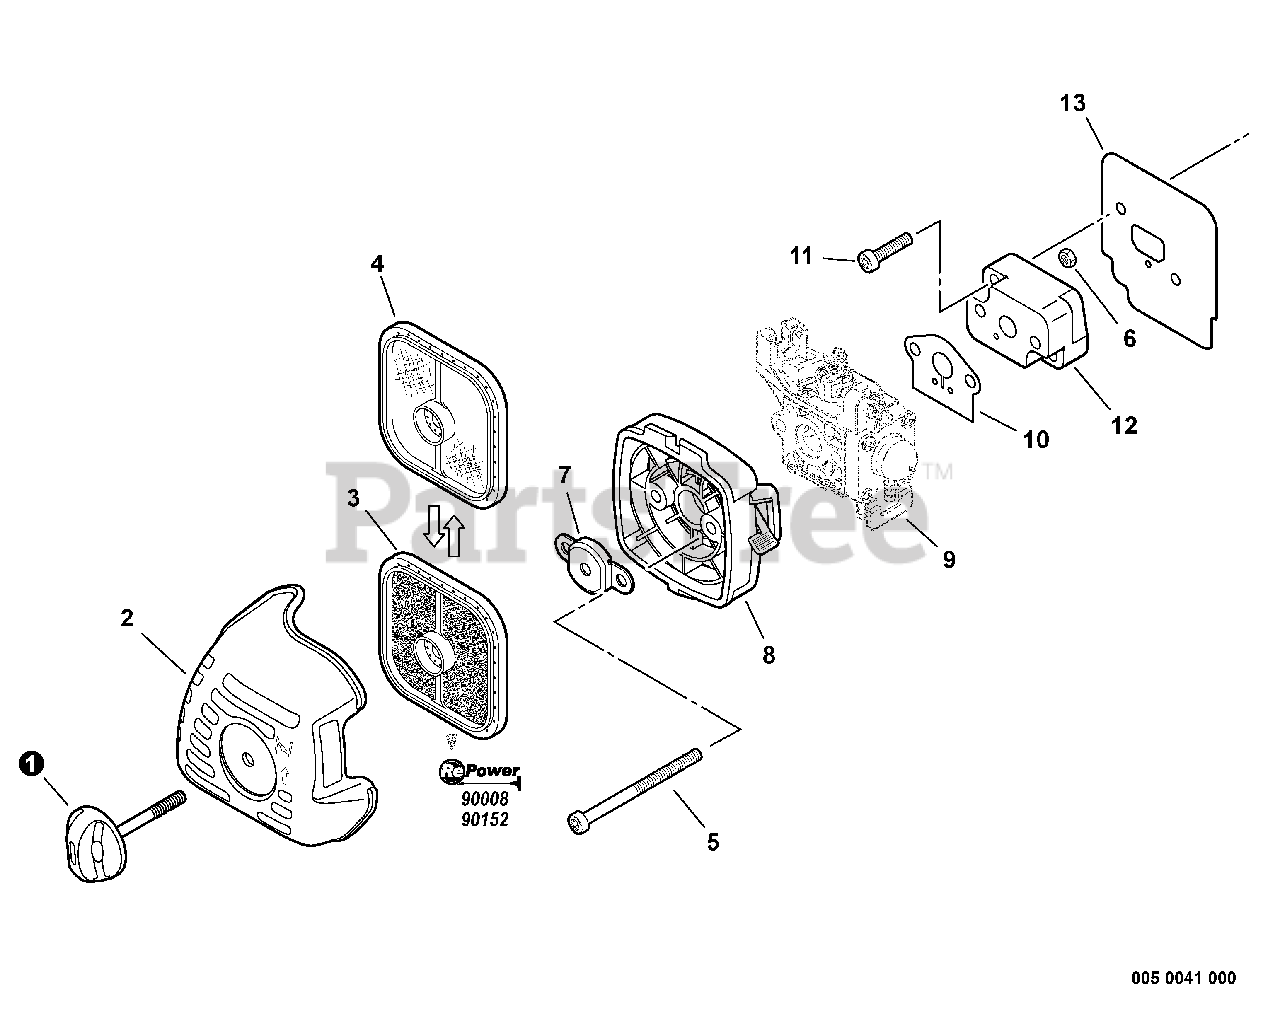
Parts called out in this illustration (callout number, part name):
1	THUMBSCREW
2	COVER, AIR FILTER
3	FILTER, AIR - DOUBLE LAYER
4	FILTER, AIR - SINGLE LAYER
5	SCREW - 5X65
7	PLATE, PREVENT
8	CASE, AIR FILTER
9	CARBURETOR
10	GASKET, INTAKE
11	SCREW - 5X20
12	INSULATOR, INTAKE
13	SHIELD, INTAKE
14	RePower TUNE-UP KIT
15	RePower FILTER KIT
